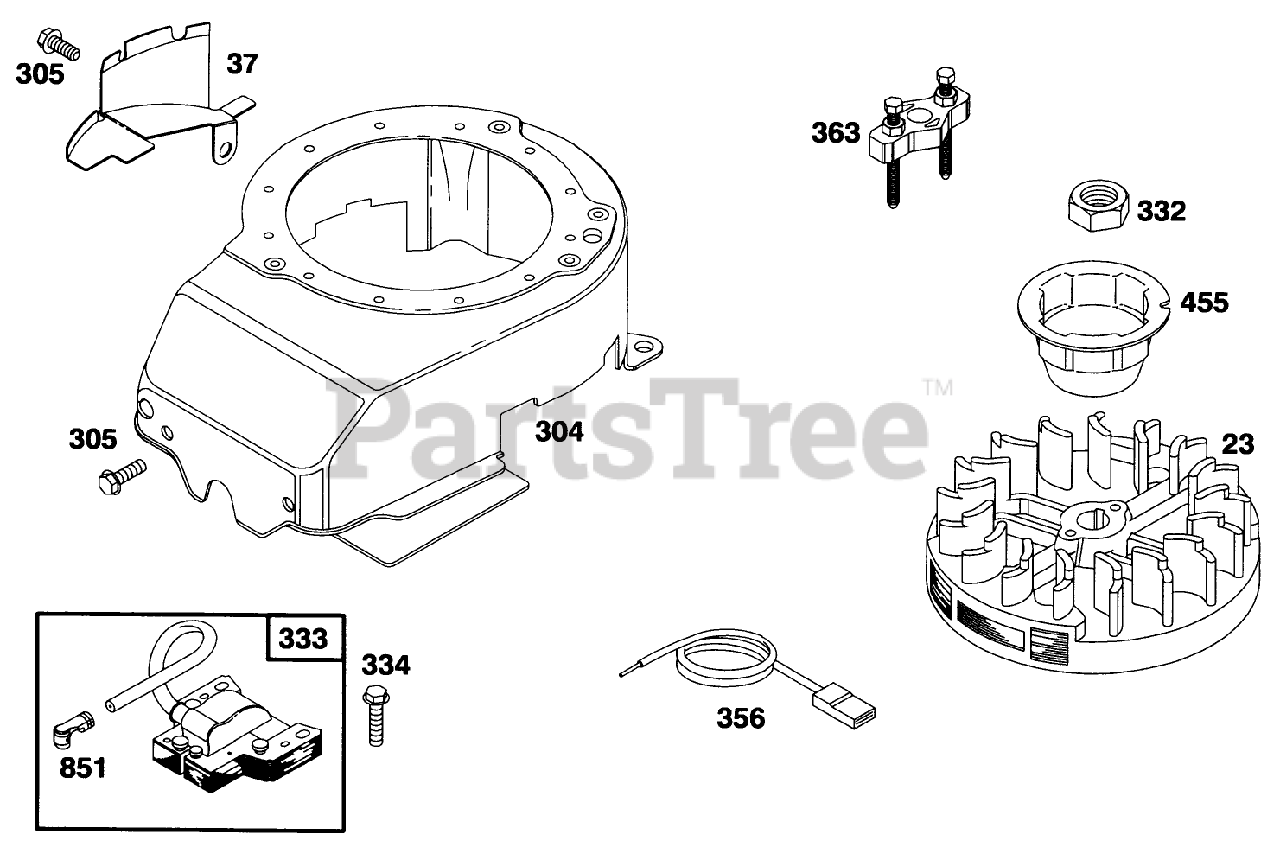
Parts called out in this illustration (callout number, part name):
23	Flywheel
37	Flywheel Guard
304	Housing-Blower
305	Screw-Hex
333	Armature-Magneto
334	Screw-Sem
356	Wire Stop
363	Puller-Flywheel
851	Terminal-Spark Plug
